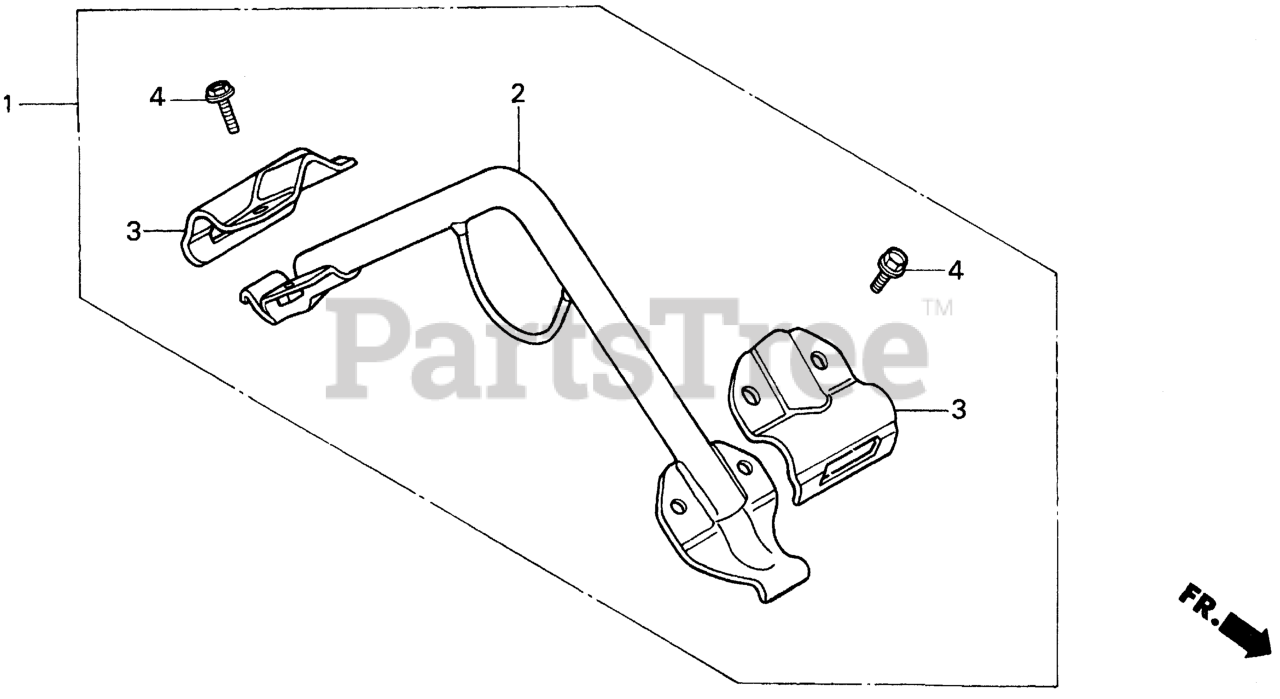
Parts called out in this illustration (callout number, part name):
1	HANGER KIT
2	HANGER
3	BRACKET, HANGER (UPPER)
4	BOLT, FLANGE (8X16) Use from Engine SN 1000016.
